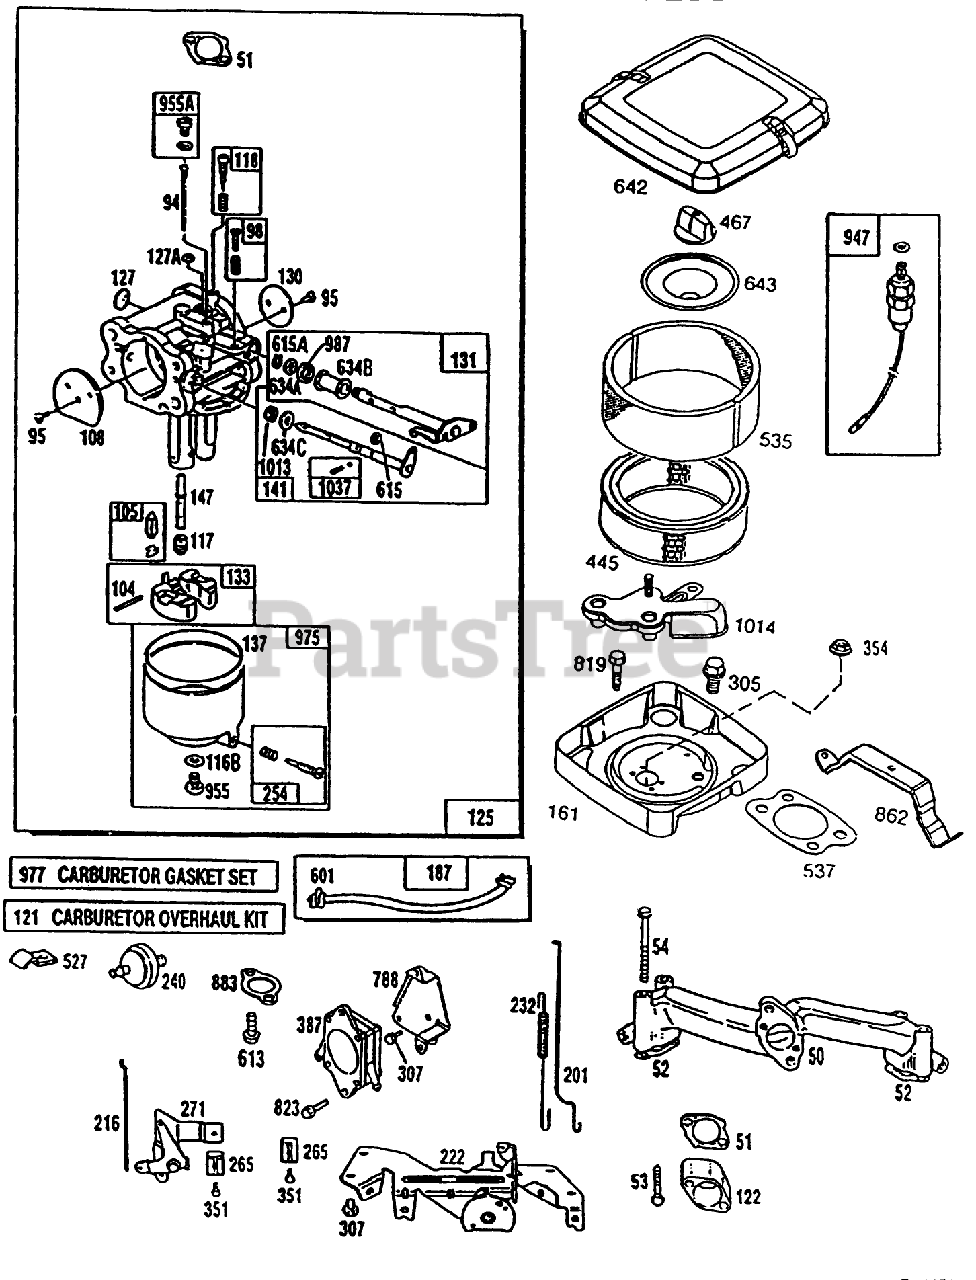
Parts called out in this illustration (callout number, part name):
50	BRIGGS-805409
51	BRIGGS-805149
52	BRIGGS 805023
53	BRIGGS-805360
87	BRIGGS-805054
95	BRIGGS-805561
98	BRIGGS 807705
104	BRIGGS 805586
105	BRIGGS 807706
118	BRIGGS-807707
121	BRIGGS-807962
122	BRIGGS-805329
125	BRIGGS-808255
127	BRIGGS 805570
127A	BRIGGS 805571
131	BRIGGS-807709
133	BRIGGS-807710
137	BRIGGS-807716
141	BRIGGS-807711
147	NOZZLE
161	Base-Air Cleaner
201	BRIGGS 805480
216	BRIGGS-805439
222	BRIGGS-807610
254	BRIGGS-807713
305	BRIGGS 805406
307	BRIGGS-78-4310
351	BRIGGS 805169
445	CARTRIDGE-CLEANER, AIR
467	BRIGGS-491875
535	ELEMENT-FILTER
537	BRIGGS 805655
601	BRIGGS-93053
615	BRIGGS 805578
615A	BRIGGS 805577
634A	BRIGGS 805576
634B	BRIGGS-805574
634C	BRIGGS 805580
643	BRIGGS 805631
819	BRIGGS 805057
823	BRIGGS 805317
955	BRIGGS 805592
955A	BRIGGS-807714
975	BRIGGS-807715
977	BRIGGS 807716
987	BRIGGS 805575
1013	BRIGGS 805581
1037	BRIGGS 807717
